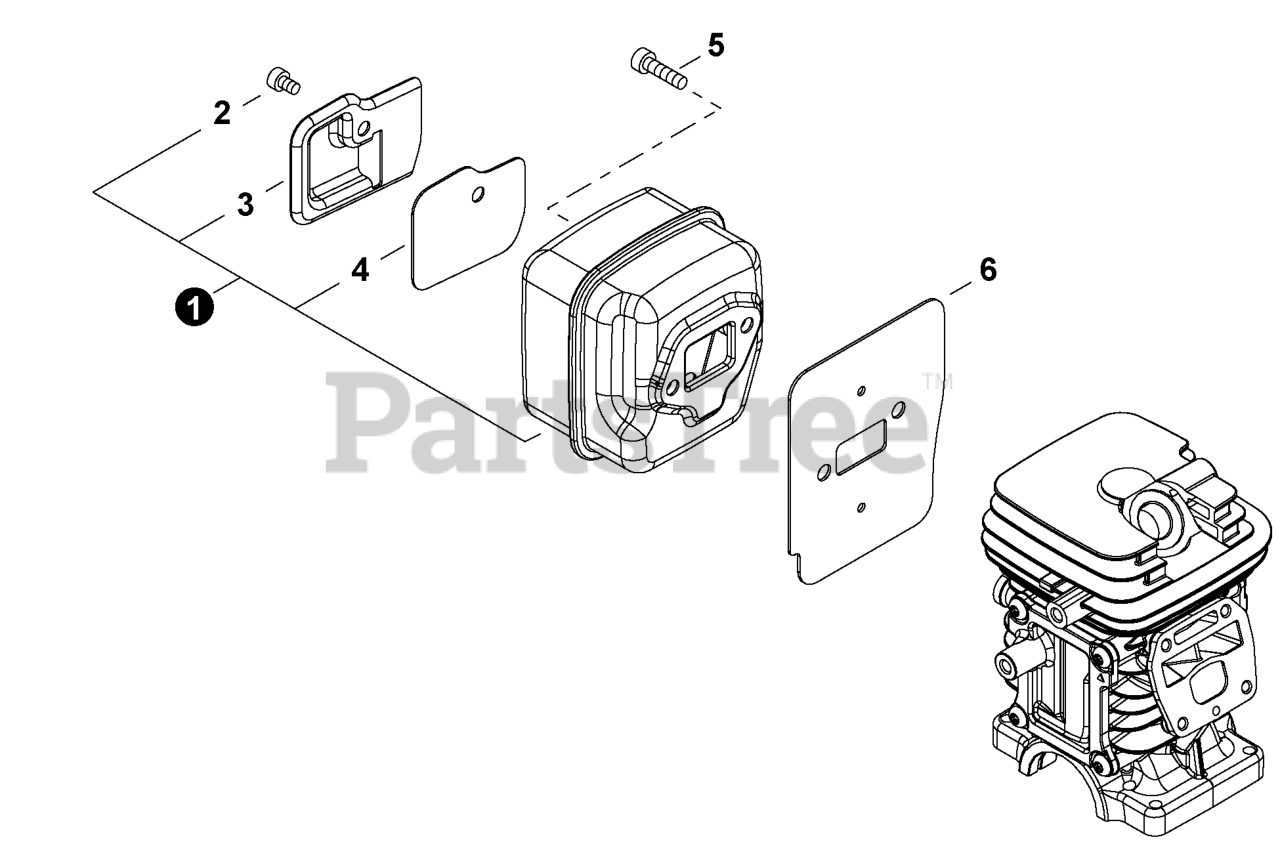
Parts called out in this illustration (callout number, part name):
1	MUFFLER ASSY
2	BOLT, TORX 5x8
3	GUIDE, EXHAUST
4	SCREEN, SPARK ARRESTER
5	BOLT, TORX 5x16
6	GASKET, EXHAUST
